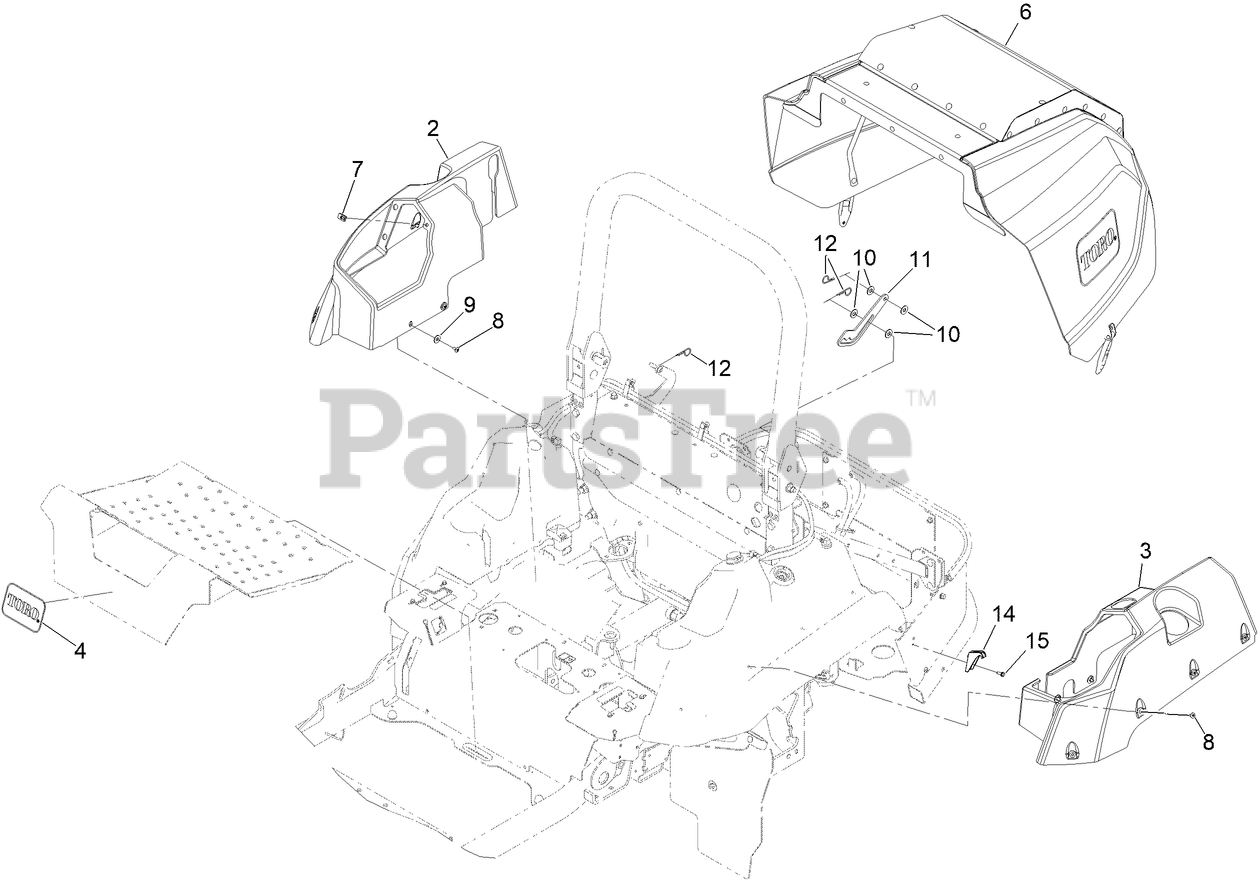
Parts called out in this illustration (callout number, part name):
2	COVER-TANK, RH
3	COVER-TANK, LH
4	DECAL
6	HOOD ASM
8	SCREW-TORX
9	WASHER-FLAT
10	WASHER-FLAT
11	PROP-HOOD
12	PIN-COTTER, HAIR
14	LATCH-CATCH
15	SCREW-HWH
